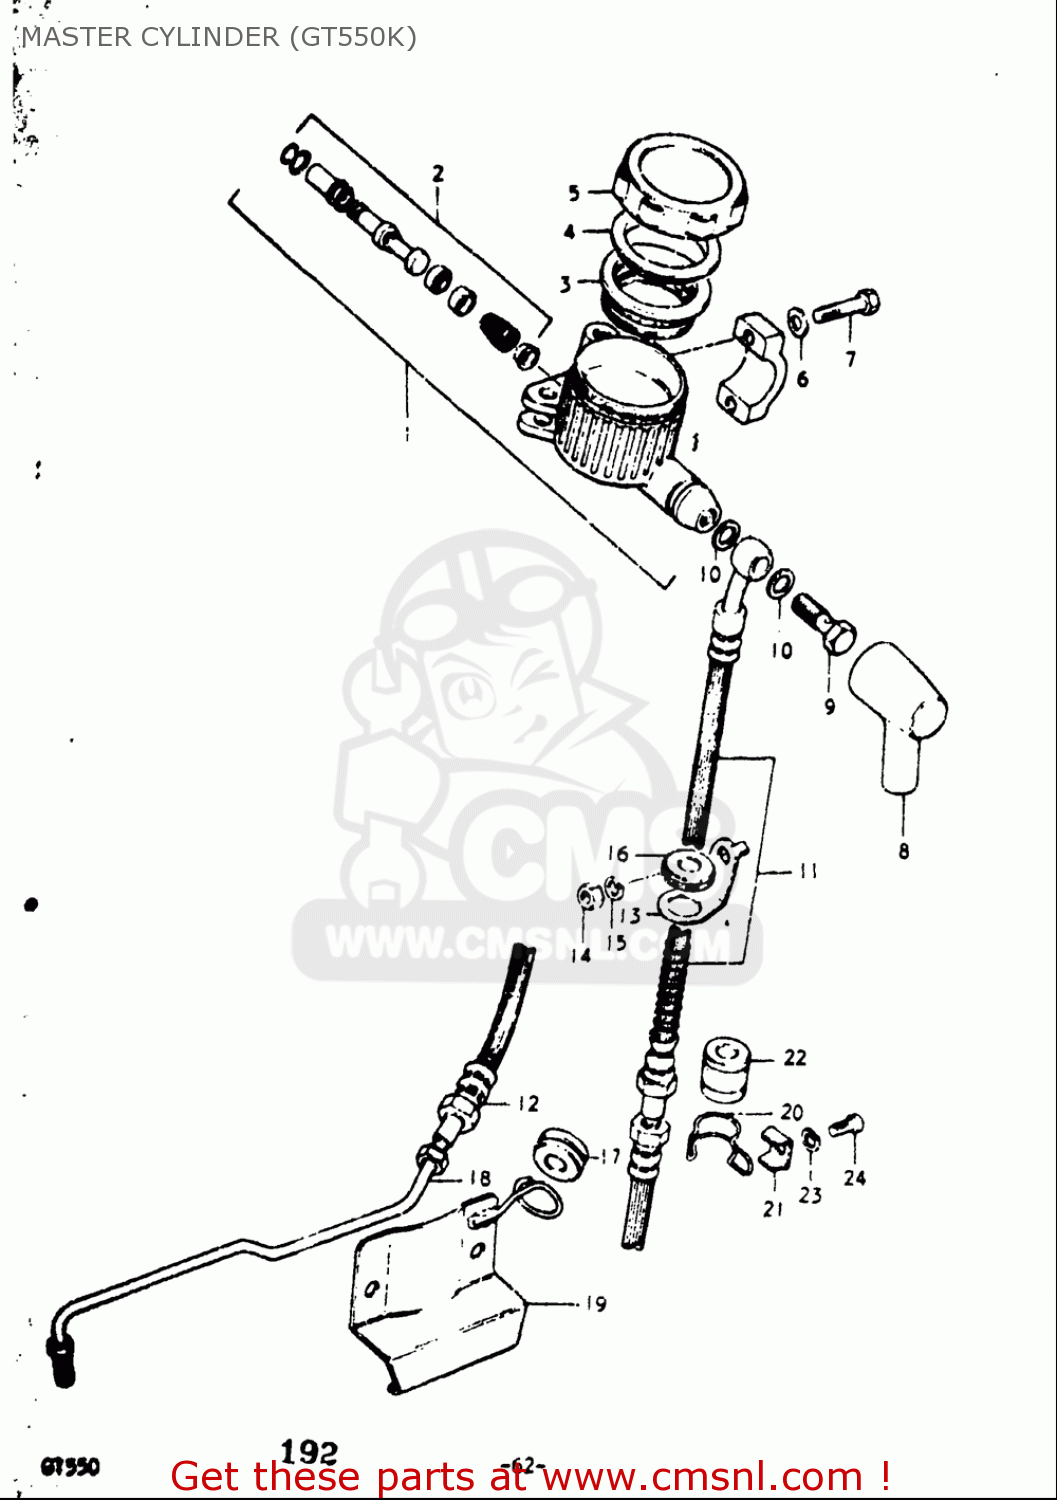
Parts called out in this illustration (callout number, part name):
2	PISTON & CUP SET
3	DIAPHRAGM
6	WASHER(6.5X20X1.6)
7	BOLT
8	BOOT,MASTER CYLINDER
9	BOLT UNION
10	WASHER(10X15X1.5)
14	NUT
15	WASHER,LOCK
16	GROMMET
23	WASHER,LOCK
24	SCREW(6X12)
